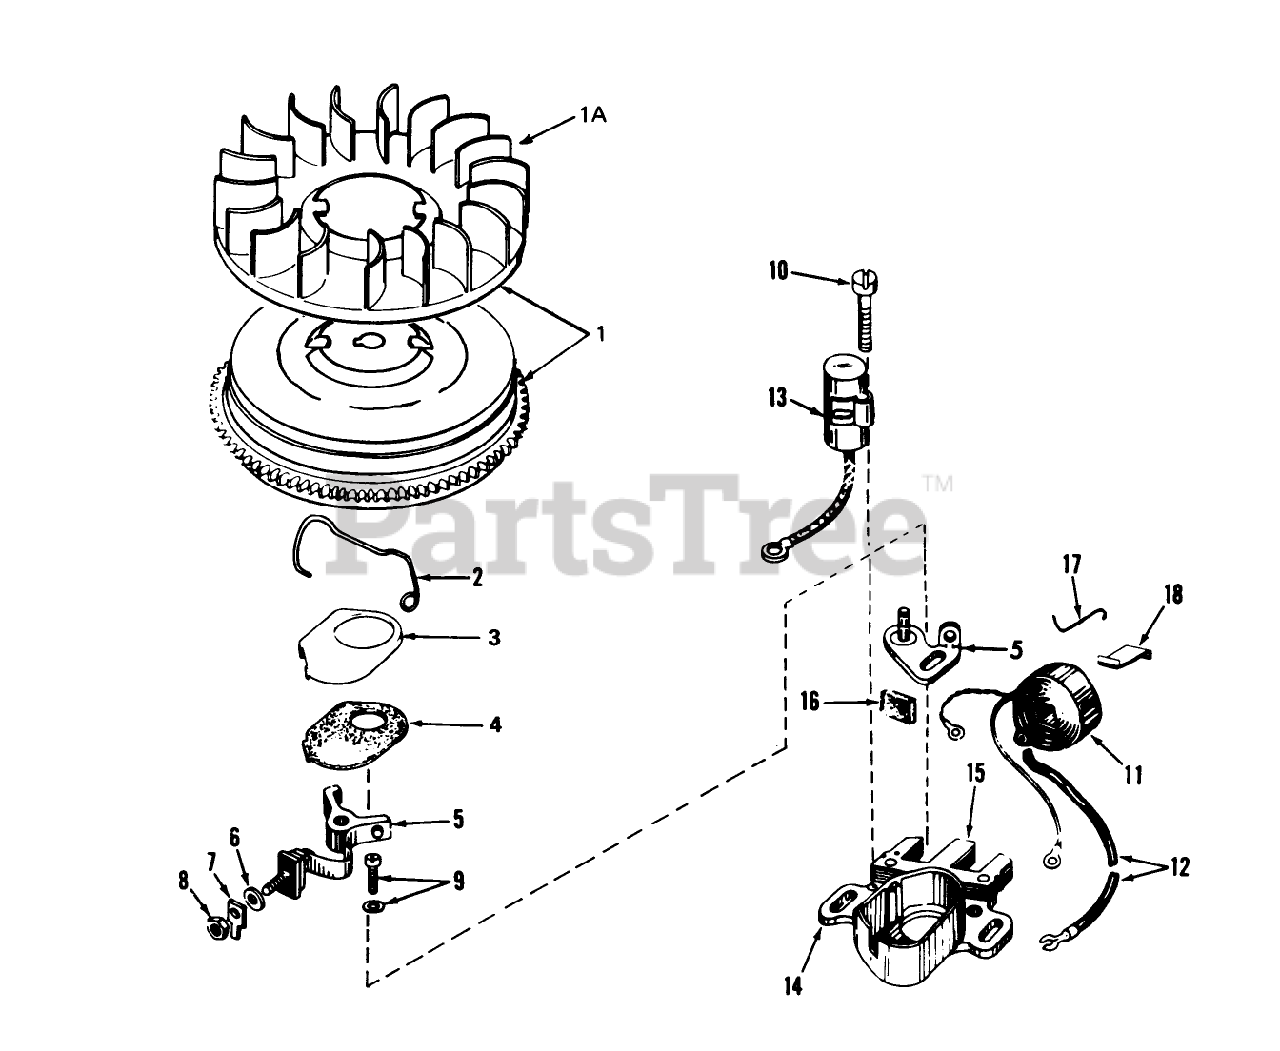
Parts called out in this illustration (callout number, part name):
1	5247/7229/68/R7268/
1A	Fan
2	Spring Breaker Box
3	Cover-Dust
4	Gasket, Dust Cover
5	Breaker Assy.
6	Washer
7	Terminal, Ground
8	DECAL
9	Breaker Screw
10	Condenser Screw
11	Coil Assy. (Incl. No. 12)
12	Wire, Lead
13	Condenser
14	Core Plate
15	Stator Assy. (Incl. Ref. #2 thru 11, 13, 14, 16, 17 19)
16	Felt,Cam Wiper
17	Clip, Coil
18	Spring Coil Wedge
